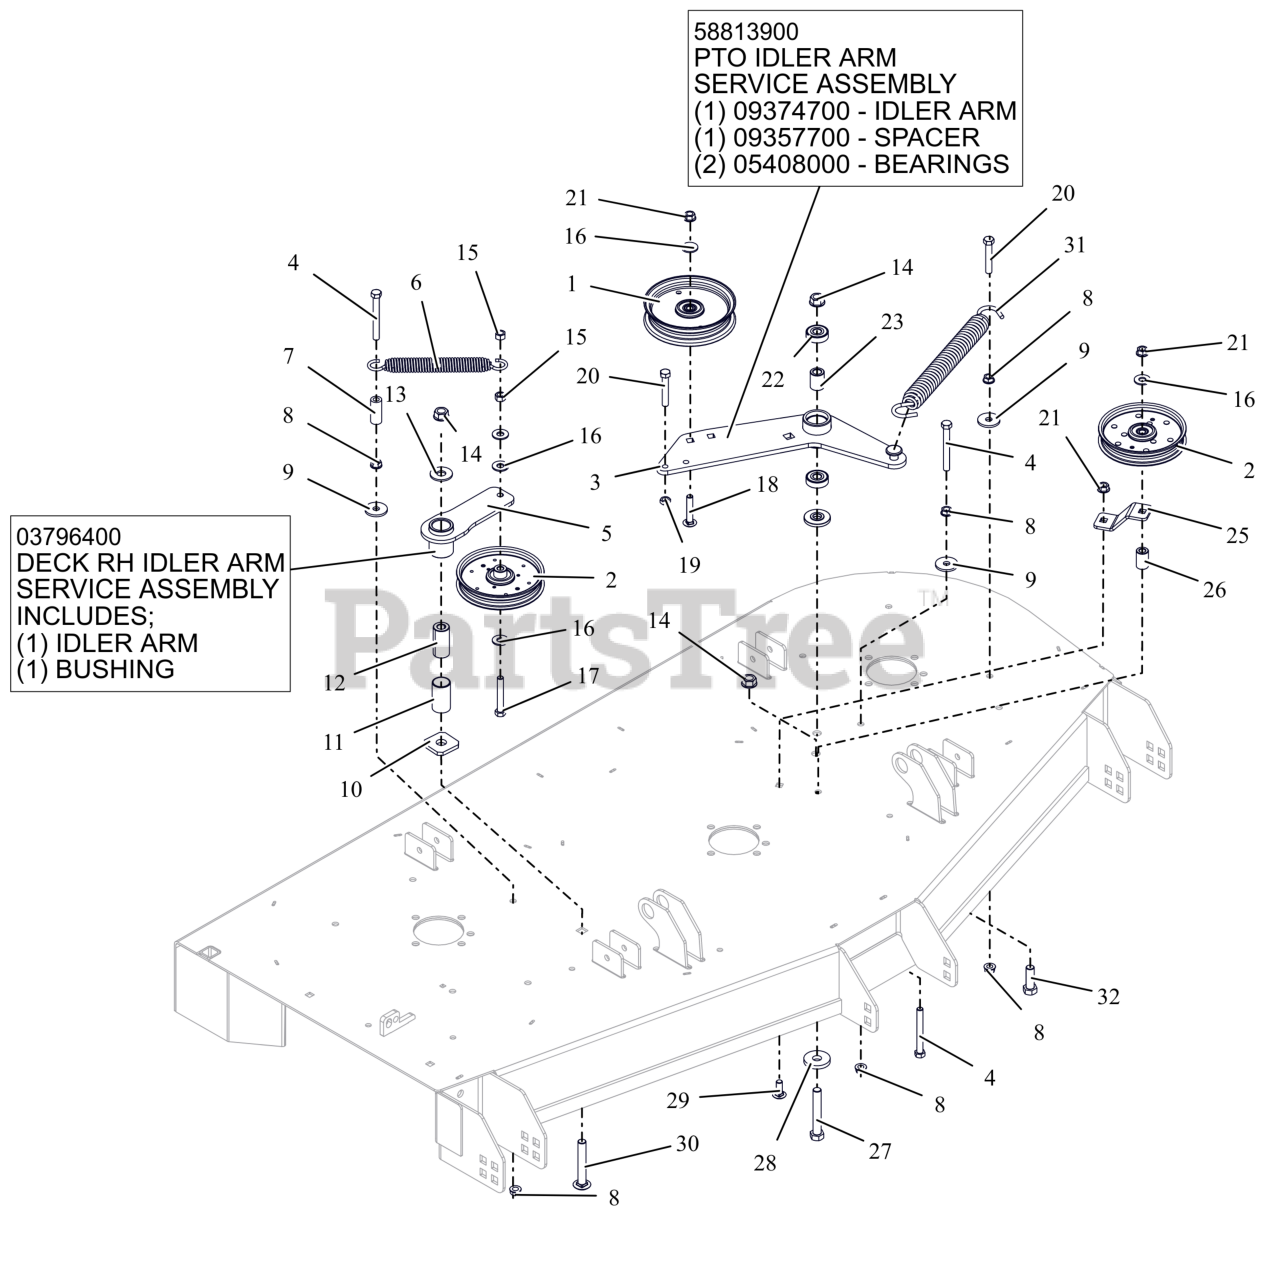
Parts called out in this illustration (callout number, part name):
1	IDLER- FLAT - 5.00" X .75"
2	IDLER- 5" FLANGED
3	WLDMT, IDLER ARM PT660
3	PTO IDLER ARM
3	SPACER .510 X .867 X 1.1485
3	BRG-BALL .500X1.38X.437
4	BLT, HEX .38-16X3.25 G5 ZCC
5	WMT, IDLER ARM - BLACK
5	ASM, IDLER ARM (DECK)
6	SPRING- EXTENSION
7	HOSE, .38 X 1.65
8	NUT, SPNLK-FLG .38-16 G5 ZCC
9	WSHR,FLT .406X1.375X.135 ZCC
10	WSHR-FLT .640X1.75X.250
11	BSHG, 1.00X1.125X1.937
12	BSHG, SPCR .502X.997X2.03 PM
13	WSHR,FLT .563X1.375X.109 ZCC
14	NUT-LK-CTR-FLG .500-13 GG ZCC
15	NUT-LK-CTR .38-16 ZC120
16	WSHR,FLT .438X1.00X.083 ZCC
17	BLT, HEX .38-16X2.50 G5 ZCC
18	BLT,RHSSN.375-16X2.00 G5 ZCC
19	NUT-JAM .375-16 G2 ZCC
20	BLT,HEX .38-16X2.25 G5 ZCC
21	NUT-LK-CTR-FLG .375-16 GF ZCC
22	BRG-BALL .500X1.38X.437
23	SPACER .510 X .867 X 1.1485
24	SPACER, IDLER ARM
25	BRKT, PTO FIXED IDLER MTG (BLACK)
26	BUSHING, SLV .380X.750X1.190
27	BLT,HEX .50-13X3.25 G5 ZCC
28	WSHR-FL-STL 0.557X1.625X0.25 ZCC
29	BLT,RHSSN .38-16X1.00 G5 ZCC
30	BTL,RHSSN .500-13 X 3.25 G5 ZCC
31	SPRING, EXTENSION
32	BLT,HEX .50-13X1.50 G5 ZCC
